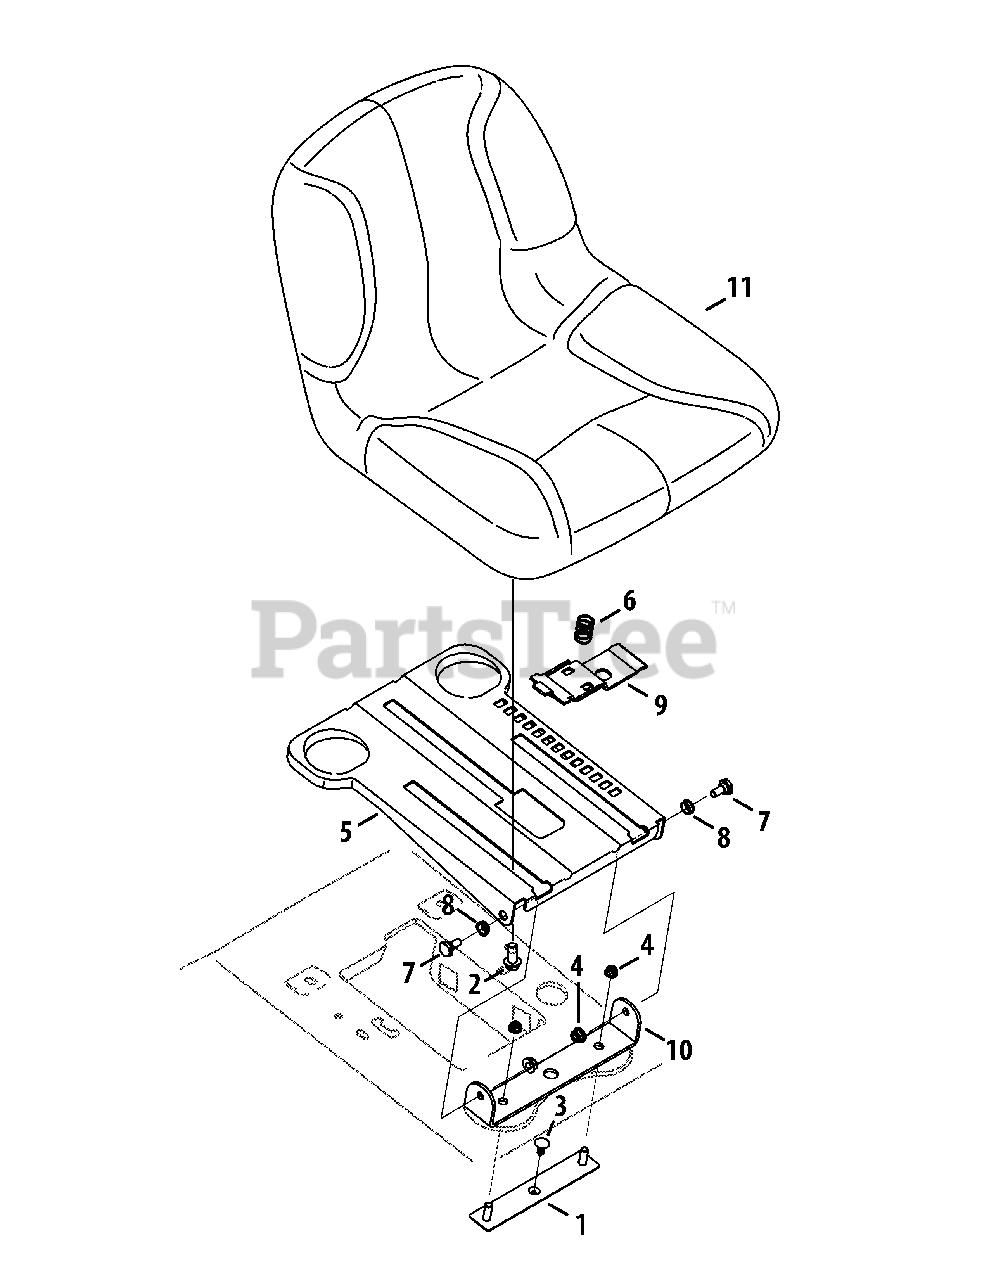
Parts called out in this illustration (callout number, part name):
1	Seat Pivot Plate Assembly
2	Hex Flange Screw, 3/8/16, .875, Gr5
3	Ratchet Clip
4	Nut, Flange Lock, 5/16-18, Grf
5	Bracket, Mounting, Seat
6	Compression Spring, .68 x 1.065 x .055
7	Shoulder Screw, .435 x .178, 5/16 x .56
8	Flange Bearing, .4385 ID
9	Seat Lever
10	Pivot Bracket, Tall
11	Seat, High
12	Arm Rest Kit
